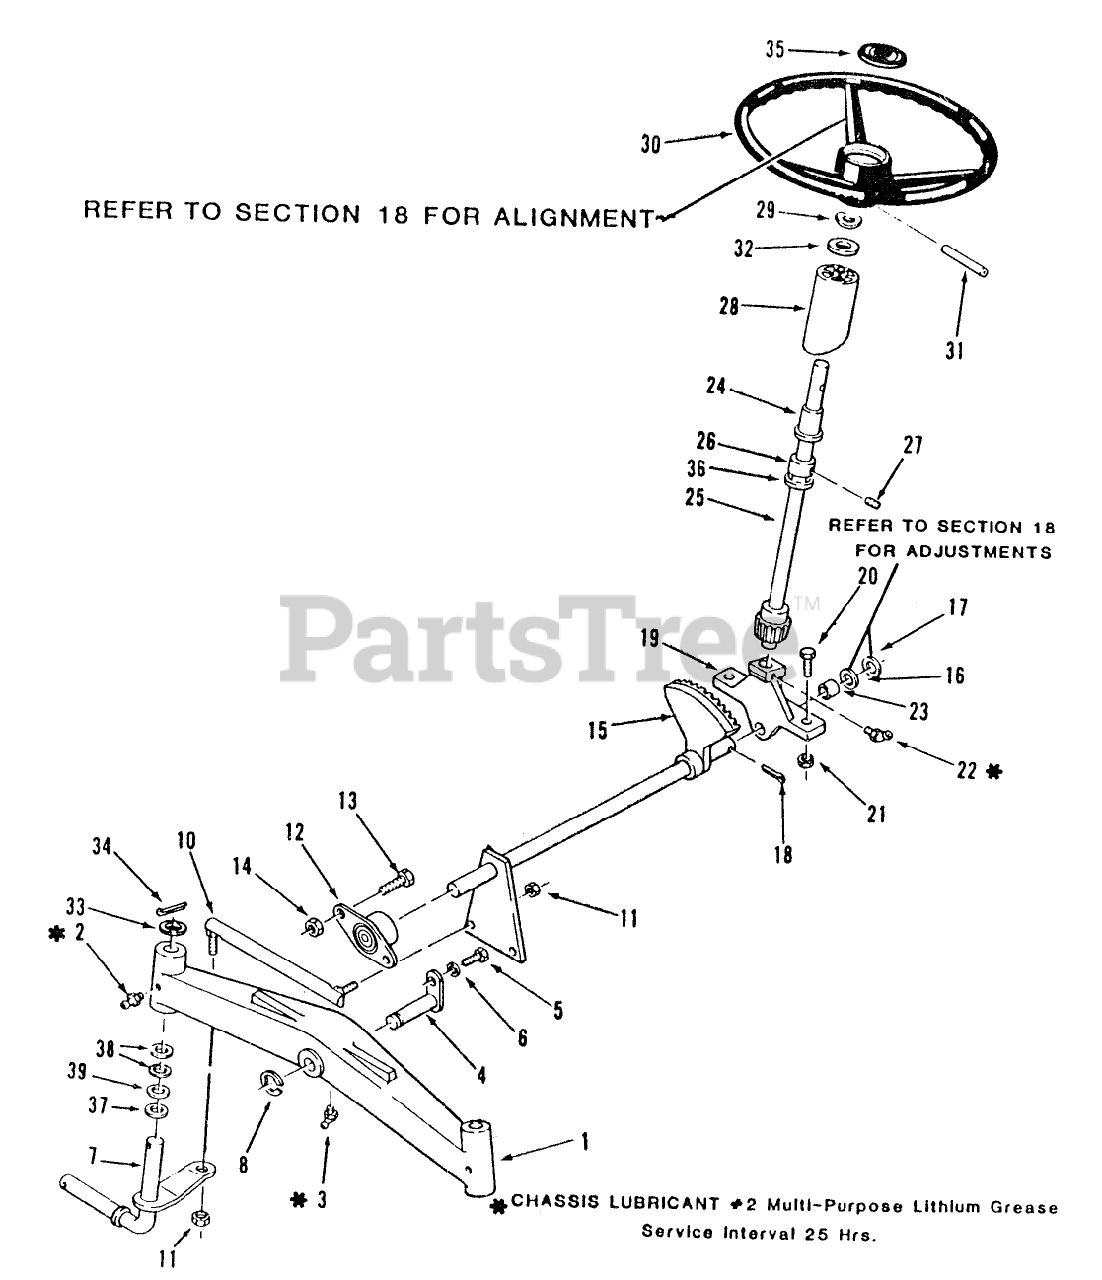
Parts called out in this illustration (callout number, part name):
3	FITTING-GREASE
4	PIN AND PLATE ASM
8	E-RING
12	BEARING-FLANGED
16	WASHER-SHIM
17	WASHER
22	FITTING-GREASE
23	BEARING-BRONZE
24	BEARING-FLANGED
29	WASHER-BOWED
30	DISCONTINE
32	WASHER-FLAT
33	WASHER
34	COTTER PIN-4
36	RING-RETAINING
39	WASHER
